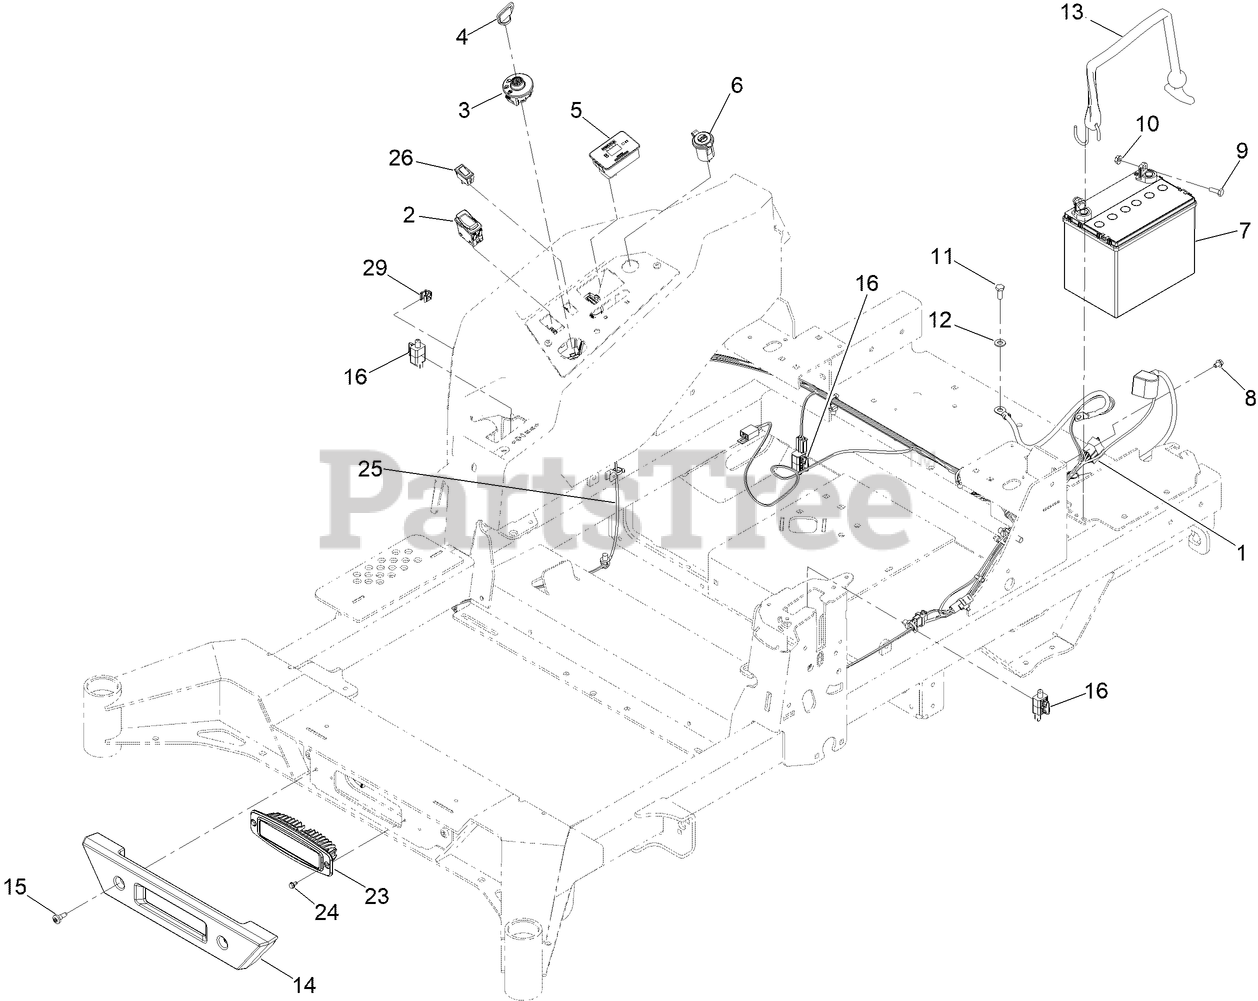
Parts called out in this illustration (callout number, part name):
1	HARNESS-WIRE, ZMASTER
2	SWITCH-ROCKER, ON-NONE-ON
3	SWITCH-IGNITION
4	KEY-IGNITION
5	MODULE ASM
6	PORT-POWER, USB
7	BATTERY-DRY
8	SCREW-HWH
9	SCREW-HH
10	NUT-HF
11	SCREW-HH
12	WASHER-PLAIN
13	STRAP, BUNGEE
14	BUMPER-FRONT
15	SCREW-SHOULDER
16	SWITCH
23	MOUNT-FLUSH, LIGHT
24	SCREW-HWH
25	HARNESS-WIRE, LIGHT KIT
26	SWITCH-ROCKER
29	CLIP-EDGE W/TIE, PERPENDICULAR
99	KEYS-IGNITION (SPARE PAIR)
